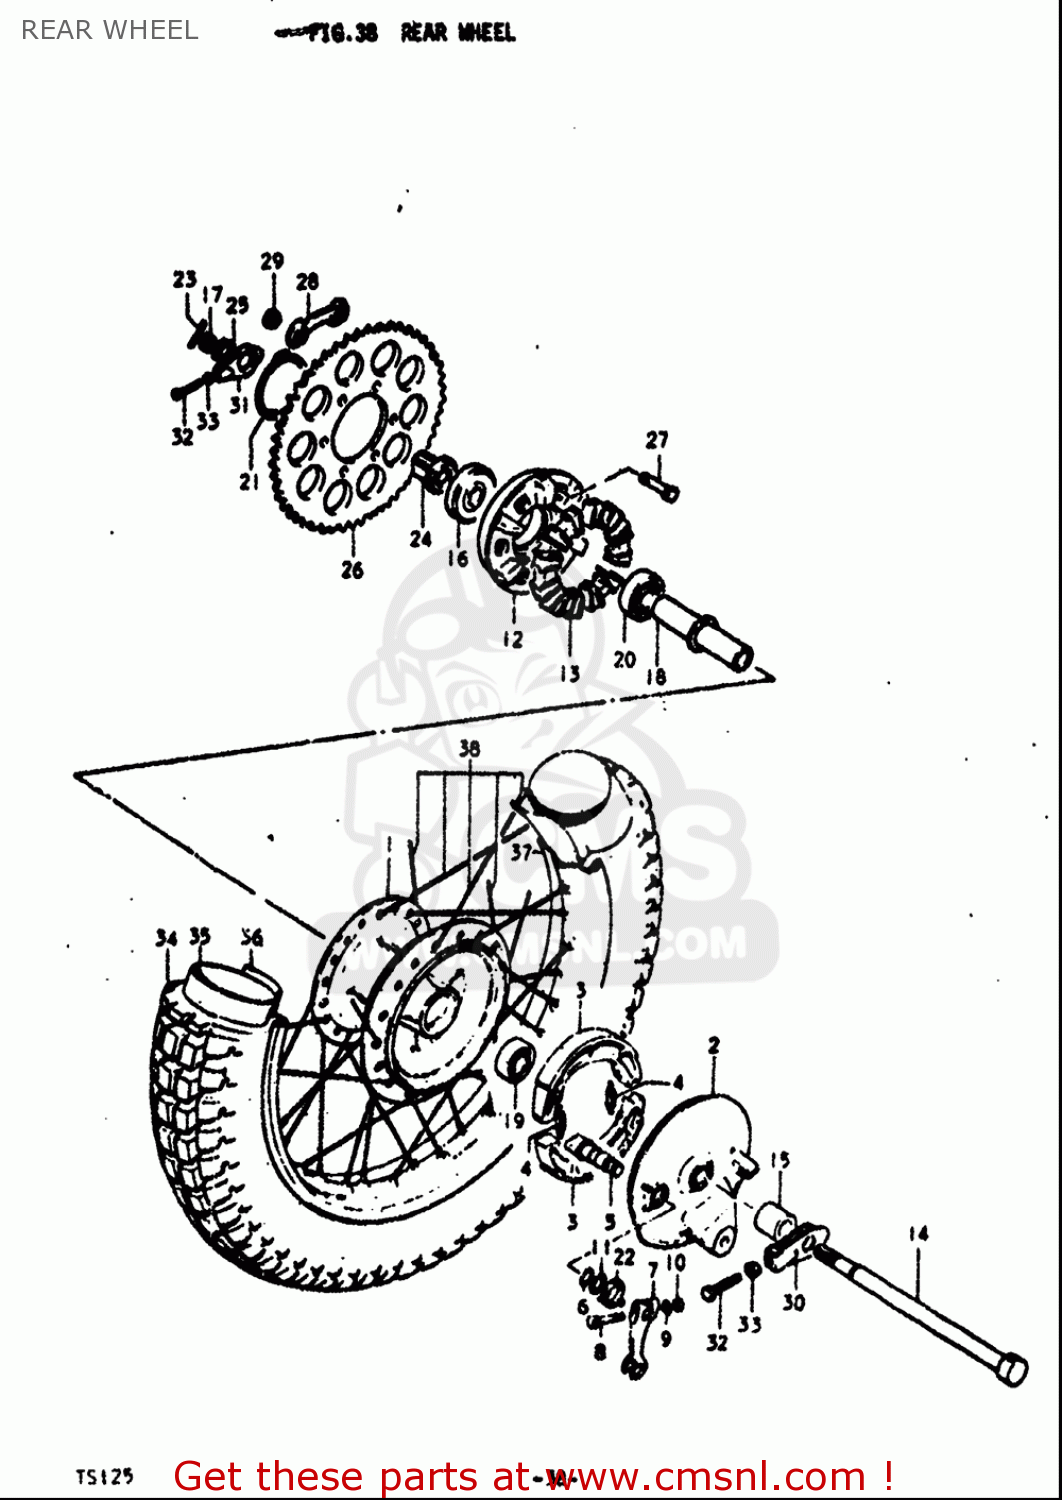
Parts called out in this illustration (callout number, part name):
4	SPRING(L:35.8)
6	O RING(D:2.5,ID:11.4)
8	BOLT(6X31)
9	WASHER
10	NUT
11	WASHER(12.5X20X1)
13	ABSORBER,RR WHEEL HUB SHOCK
14	AXLE,REAR
15	SPACER(15.2X22X26)
16	SPACER,RR AXLE,L
17	NUT 12MM
19	BEARING
20	B1 15X42X13 BEA
21	CIRCLIP
22	SPRING
23	PIN
24	SPACER,CHAIN ADJUSTER,L
25	NUT
26	SPROCKET,RR
27	BOLT(8X32)
28	WASHER
29	NUT
30	ADJUSTER,CHAIN
31	ADJUSTER,CHAIN,L
32	BOLT(6X38)
33	NUT
35	TUBE ASSY,INNER
36	PROTECTOR,INNER TUBE
